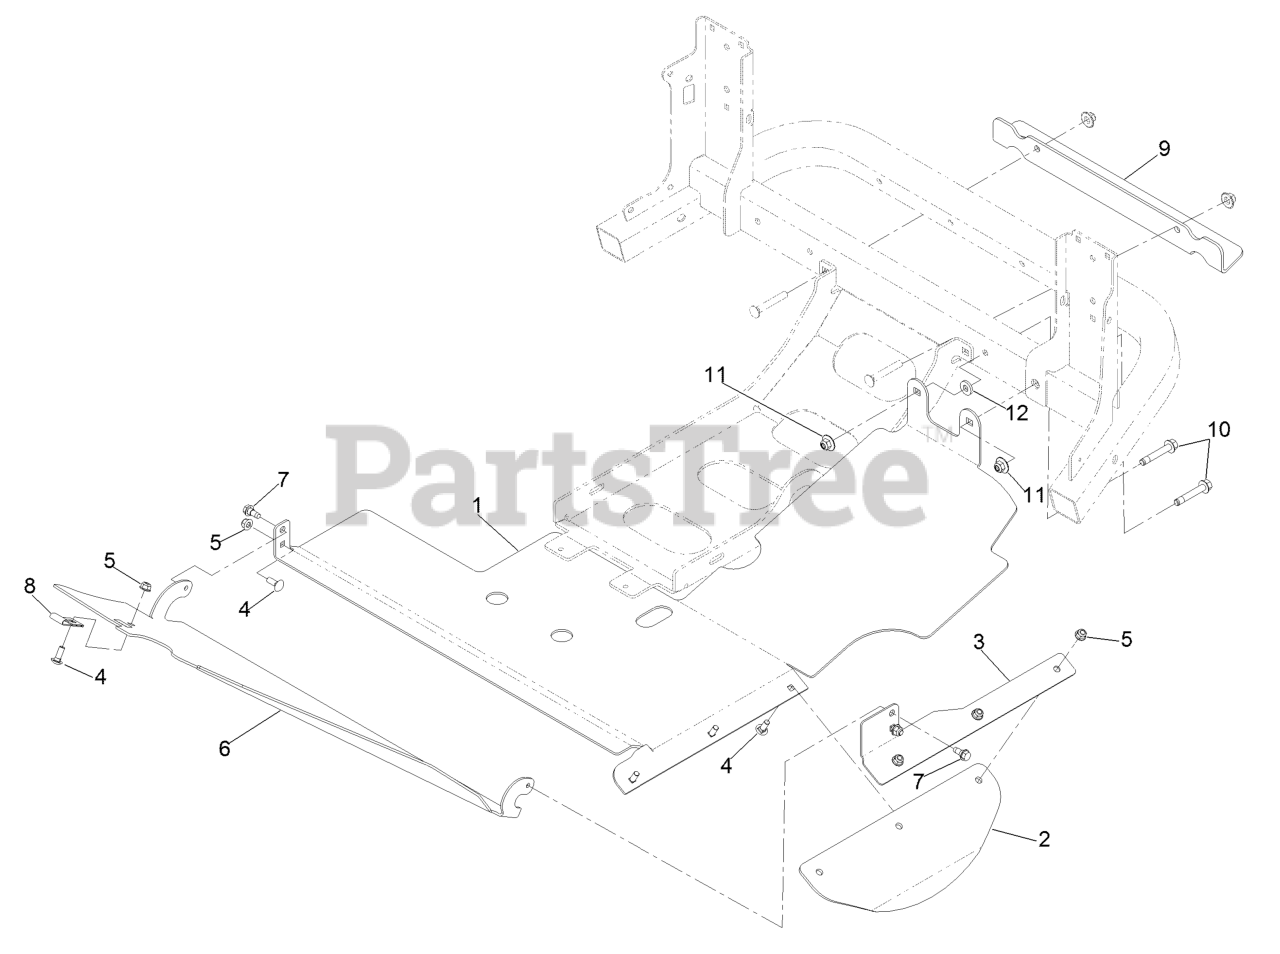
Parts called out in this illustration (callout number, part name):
1	Plate-Discharge
2	Flap-Rubber
3	Bracket-Flap, LH
4	Bolt-Carriage 5/16-18 X 7/8
5	Nut-Nyloc 5/16-18 Flg
6	Panel-Discharge
7	Screw-Shoulder
8	Bearing-Strap, Nylon
9	Bracket-Tie Down
10	Screw-HHF W/ Patch
11	Nut-Nyloc 3/8-16 Flg
